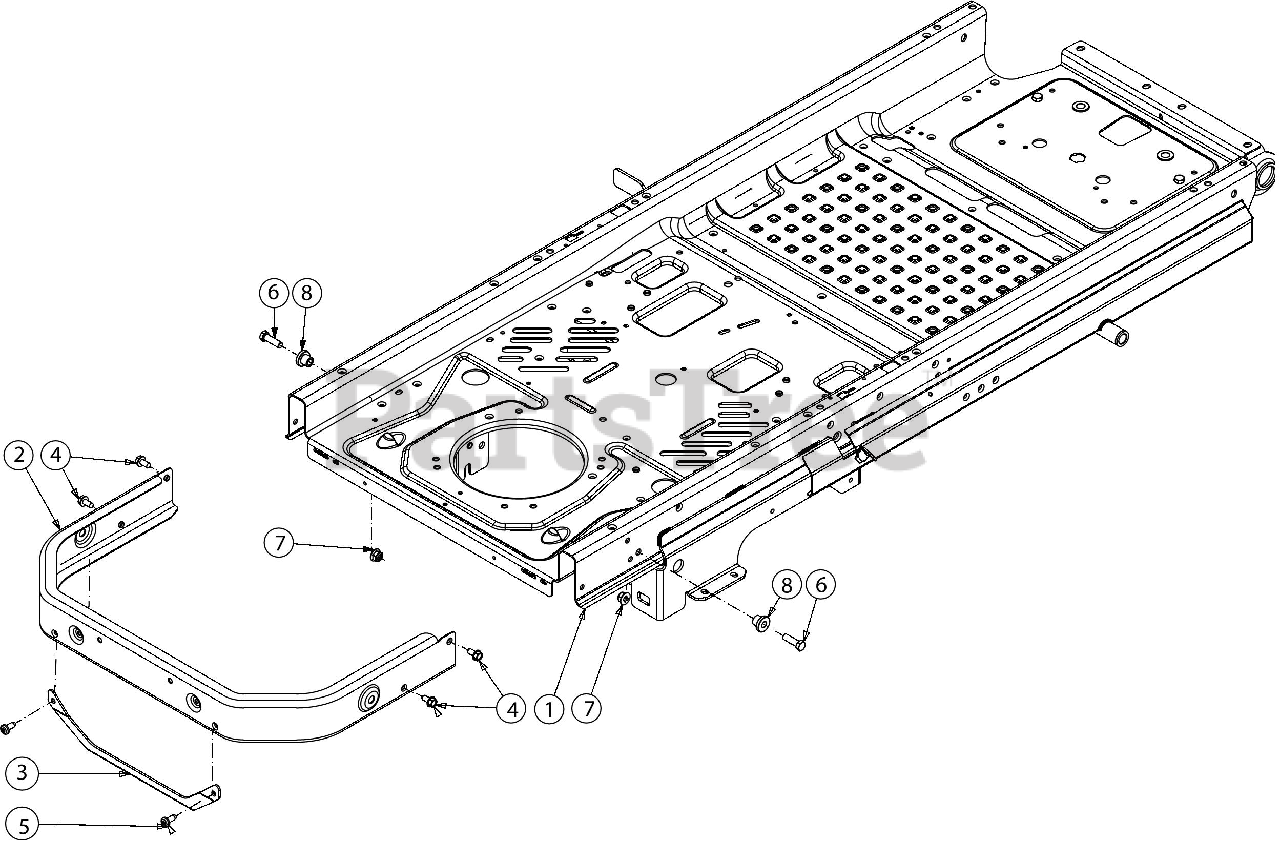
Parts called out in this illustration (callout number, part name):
4	SCREW 5/16-18 X .750
5	SCREW 5/16-18 X.75
6	SCREW 3/8-16 X 1.25 GR5
8	SHOULDER SPACER
